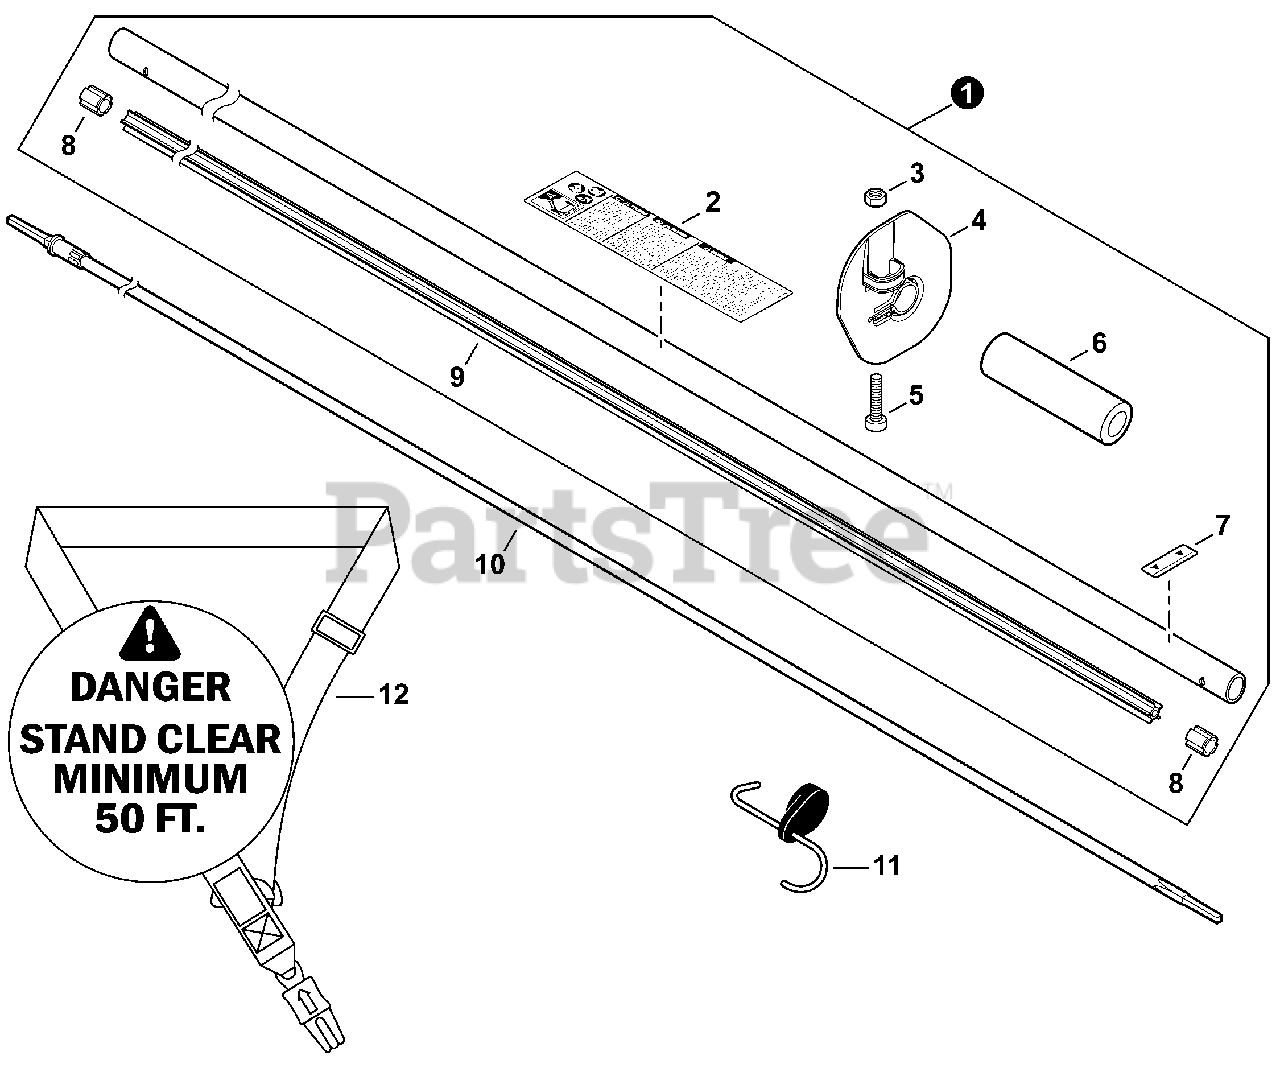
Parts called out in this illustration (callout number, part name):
1	MAIN PIPE ASSY
2	LABEL, CAUTION
3	NUT M5
4	GUARD, HAND
5	BOLT, TORX 5×20
6	GRIP, HANDLE
7	LABEL - ALIGNMENT
9	LINER - FLEXIBLE
10	DRIVESHAFT - FLEXIBLE
11	HANGER, ATTACHMENT
12	HARNESS, SHOULDER
